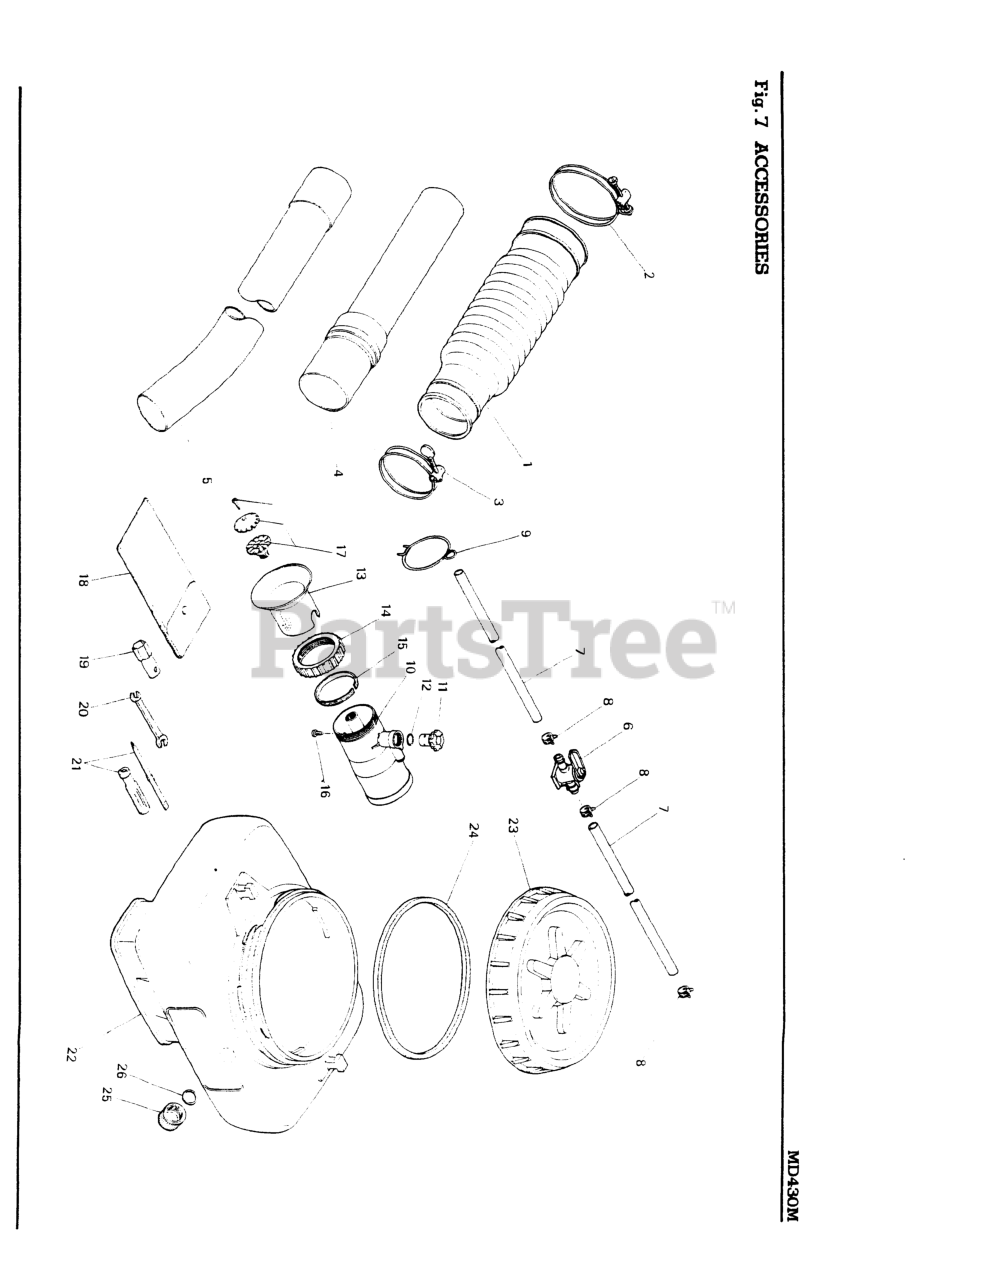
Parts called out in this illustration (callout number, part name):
2	2756-51510 (RPLS. 07280-09832)
6	COCK ASSEMBLY (NLA)
10	MIST PIPE ASSEMBLY
13	PIPE, SLIDE (NLA)
14	STOPPER (NLA)
16	SCREW, M5 X 10
21	SCREWDRIVER
23	CAP ASSY
25	CAP ASSEMBLY (NLA)
